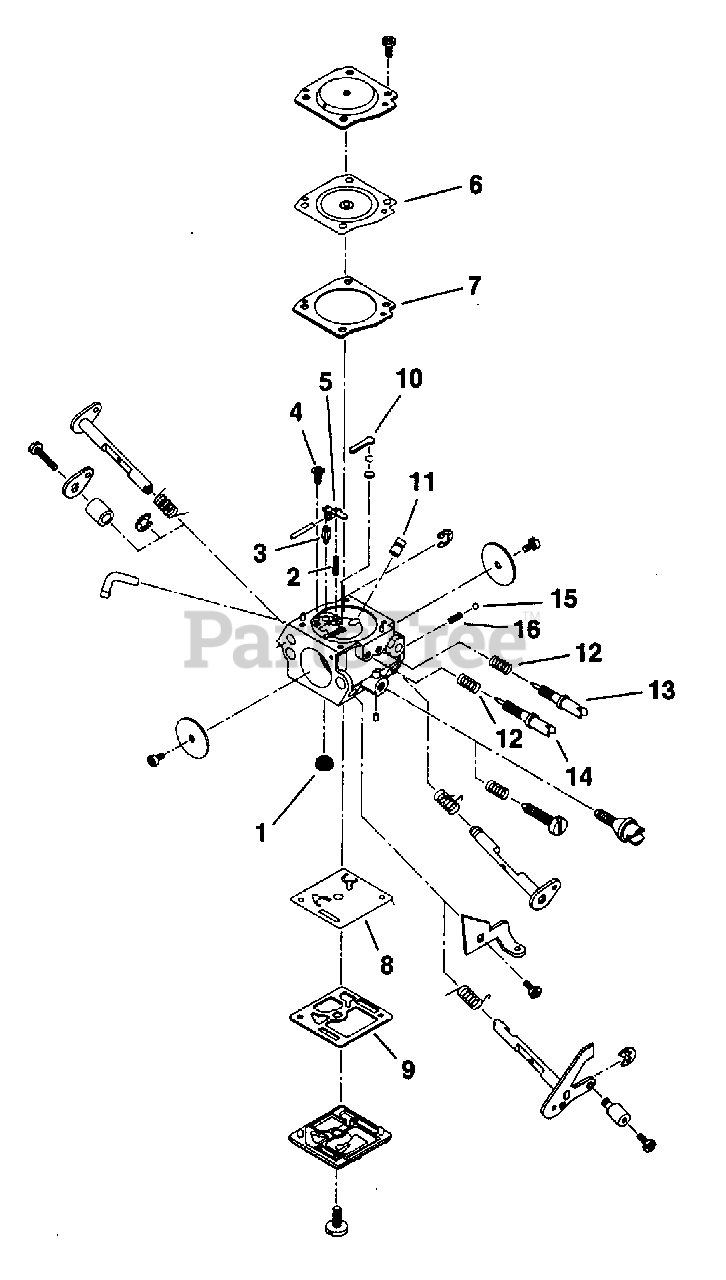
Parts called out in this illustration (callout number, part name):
1	Repair Kit
2	Repair Kit
3	Repair Kit
4	Repair Kit
5	Repair Kit
6	Repair Kit
7	Repair Kit
8	Repair Kit
9	Repair Kit
10	Repair Kit
11	Repair Kit
12	Repair Kit
13	Repair Kit
14	Repair Kit
15	Repair Kit
16	Repair Kit
